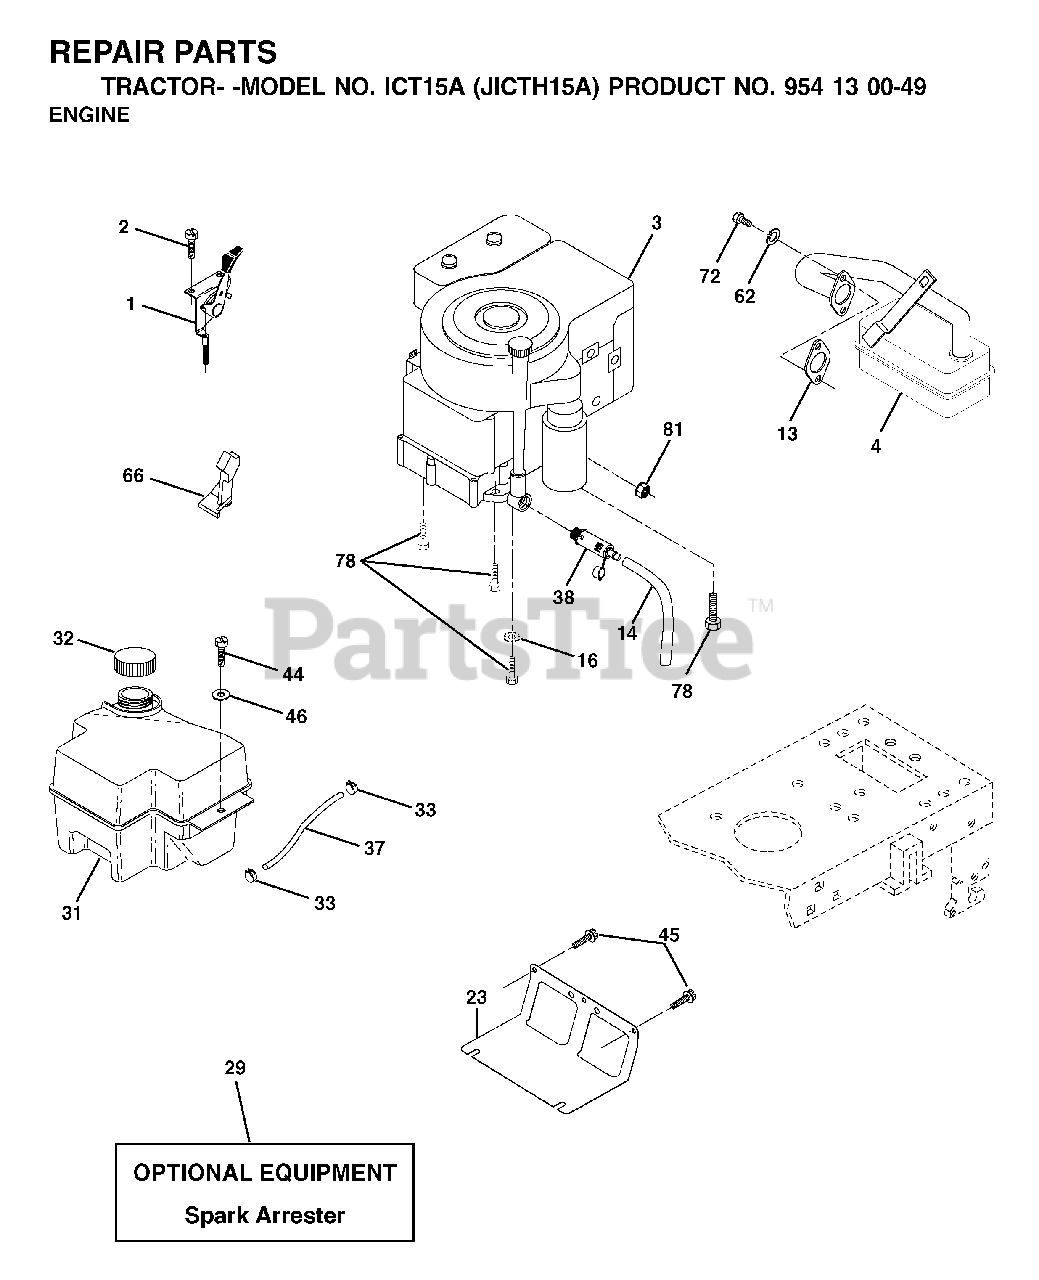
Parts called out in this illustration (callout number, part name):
1	THROTTLE CONTROL CABLE
2	SCREW LT
13	REPL BY 532 27 22-93
14	PLUG, OIL DRAIN EASY
16	LOCKWASHER
23	SHEILD.BROWNING.DBR.GUARD
29	ARRESTER SPARK (OPTIONAL)
31	TANK, 2GAL
32	FUEL CAP
33	HOSE CLAMP
37	LINE.FUEL.20
38	TUBE, DRAIN OIL ASM.
44	SCREW HEXWSHR 1/4-20X3/4
45	SCREW, 3/8-16X3/4
62	LOCKWASHER
66	STOP THROTTLE
72	SCREW
78	SCREW.3/8-16
81	NUT
